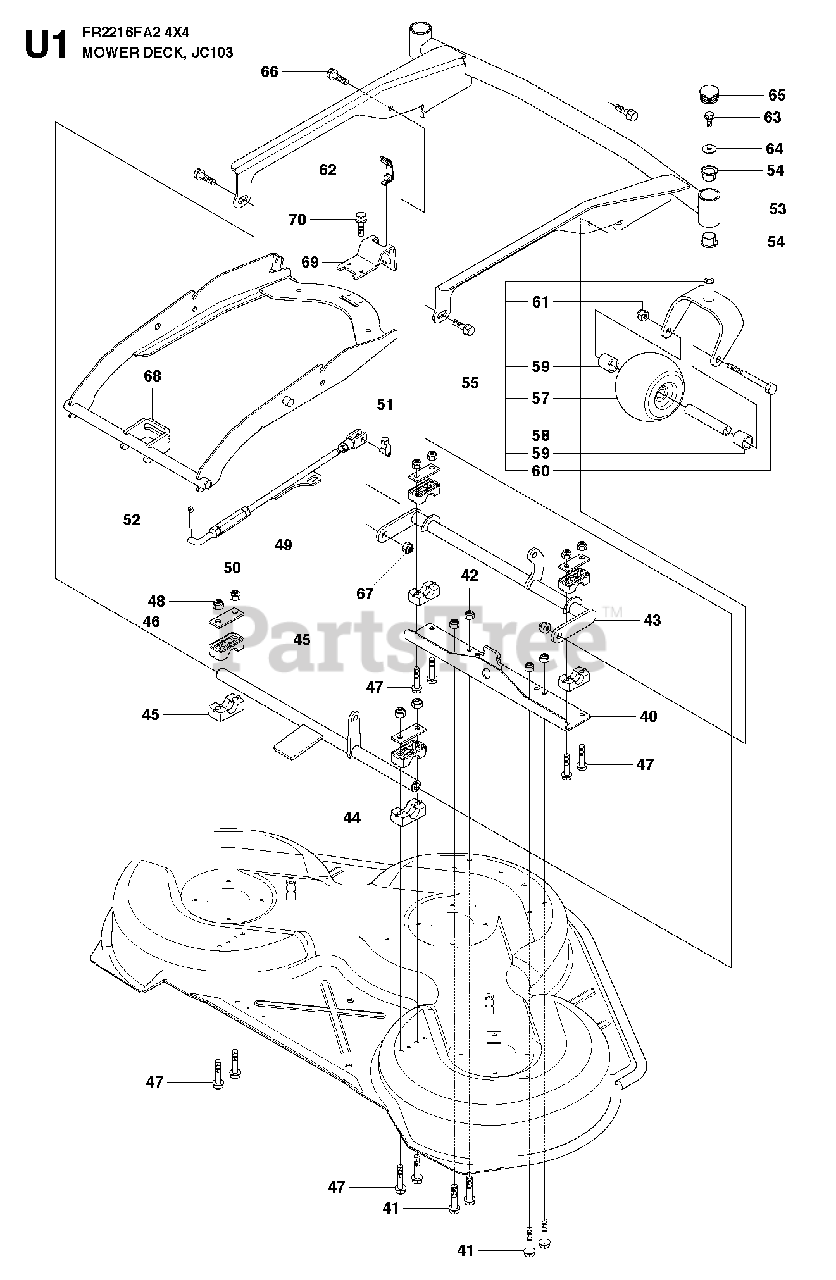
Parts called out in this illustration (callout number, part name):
42	LOCKNUT M8
48	LOCKNUT M8
49	PARALLELL ROD ASSY
50	PARALLEL ROD
51	RETAINER
52	SPLIT PIN
57	DECK ROLLER, FRONT
58	PIPE
59	SPACER
61	NUT
62	CLIP GRAY
67	LOCKNUT M8
